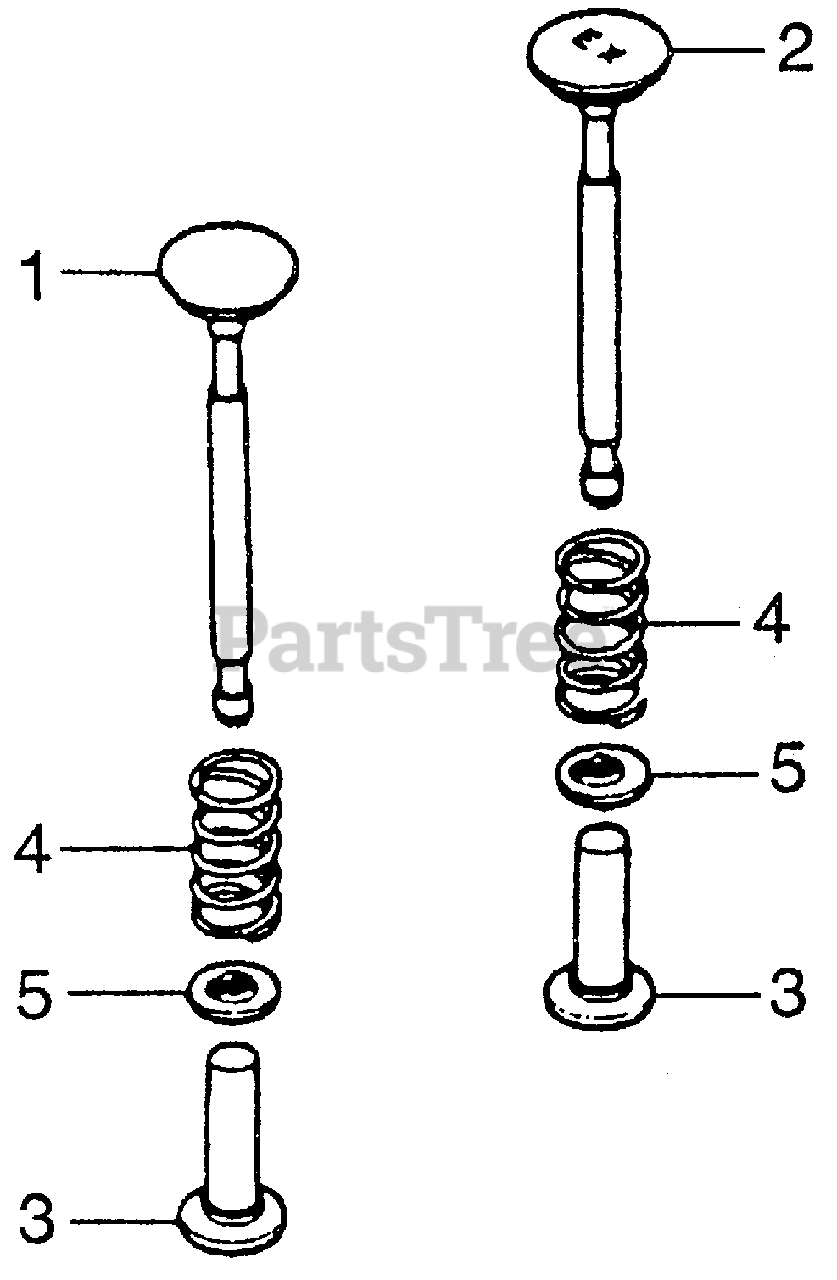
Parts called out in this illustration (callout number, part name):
1	VALVE, IN.
2	VALVE, EX.
3	LIFTER, VALVE
4	SPRING, VALVE (NOT AVAILABLE)
5	RETAINER, VALVE SPRING
